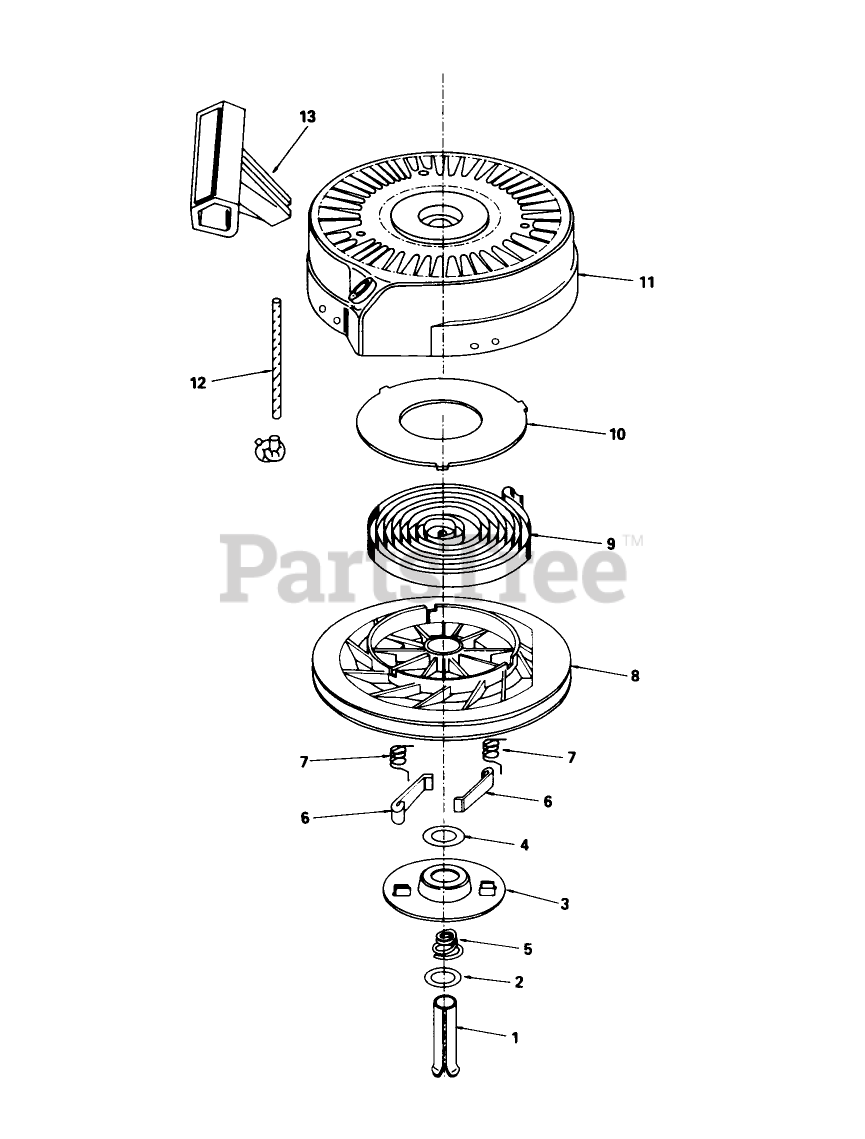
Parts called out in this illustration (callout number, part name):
1	Pin-Spring (Incl. Ref. #4)
3	Retainer
5	Brake Spring
6	Dog-Starter
7	Spring-Dog
8	Pulley
9	Rewind Spring
10	Cover-Spring
11	Housing-Starter
12	Rope-Starter (98 cut to length)
13	Handle-Starter
